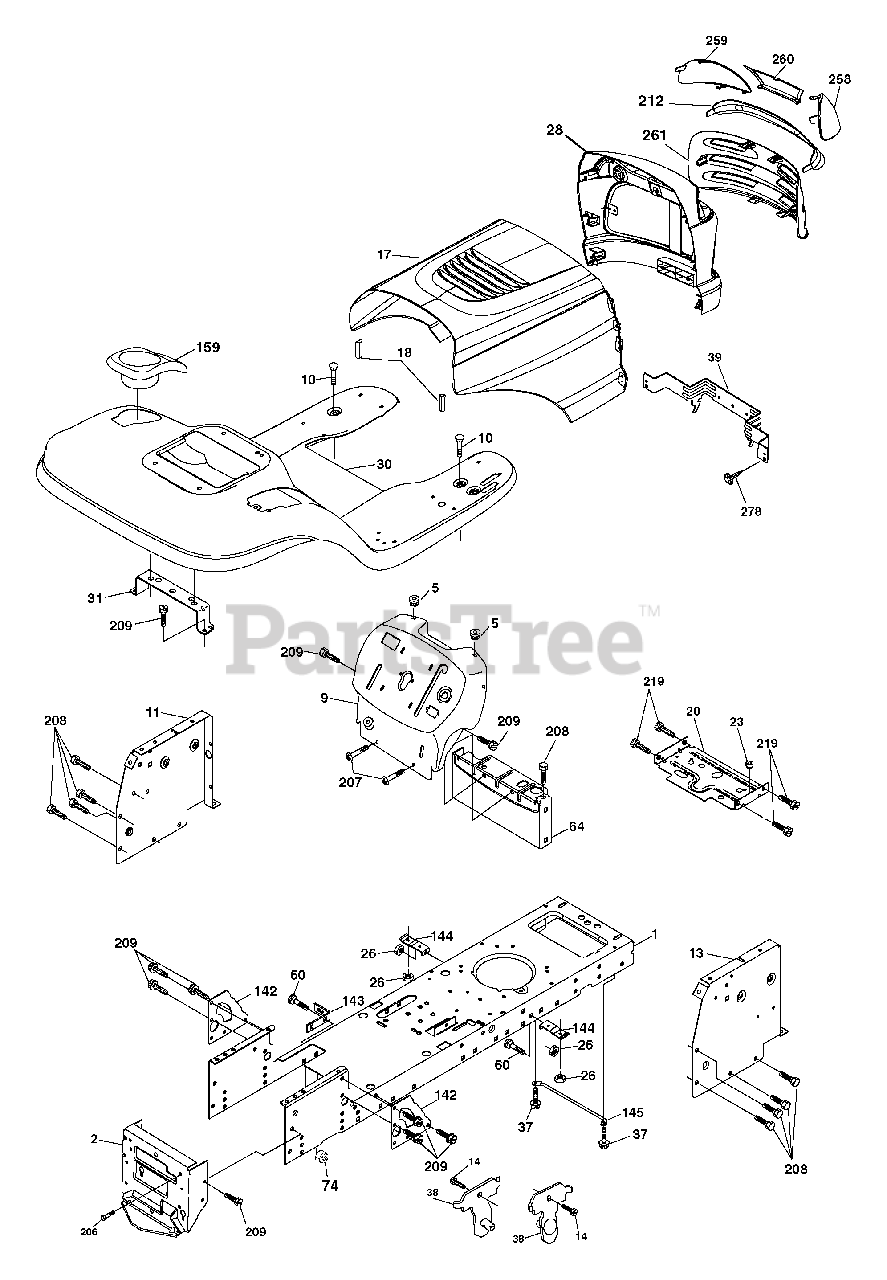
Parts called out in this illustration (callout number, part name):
1	Chassis Stamping
2	Drawbar, 12 Ga.
5	Bumper Hood/Dash
9	Dash Slkscr
10	Bolt Carriage 3/8-16 x 1
11	Panel Dash Lh
13	Panel Dash Rh
14	Screw Thdrol 3/8-16 x 1/2
17	Hood
18	Bumper Hood
20	Plate Mounting Battery
23	Bushing Snap
26	Nut Lock Hex W/Ins 3/8-16 unc
28	Grille/Lens Asm
30	Fender Footrest
31	Bracket Fender
37	Screw Thdrol 6/16-18 x 1/2 TYT
38	Bracket Asm Pivot Mower Rear
39	Bracket Pivot
60	Bolt Rd Hd Sqnk 3/8-16 unc x 3/4
64	Dash Lower STLT
74	Nut Crownlock 3/8-16 unc
142	Plate Reinforcement STLT
143	Bracket Swaybar Chassis
144	Bracket Footrest
145	Rod Pivot Chassis/Hood
159	Cupholder
166	Screw Hw Hd Hi-Lo #13-16 x 3/4
206	Bolt Shoulder 5/16-18 TT
207	Screw Thdrol 5/16-18 x 1/2
208	Screw Thdrol 3/8-16 x 1/2 Ty-tt
209	Screw Hex Wsh Thdr. 3/8-16 x 3/4
212	Insert Lens Reflective
219	Screw 5/16-18 x 3/4
258	Lens Husq Laser LT Clear RH
259	Lens Husq Laser LT Clear LH
260	Cover Lens
261	Insert Grille
